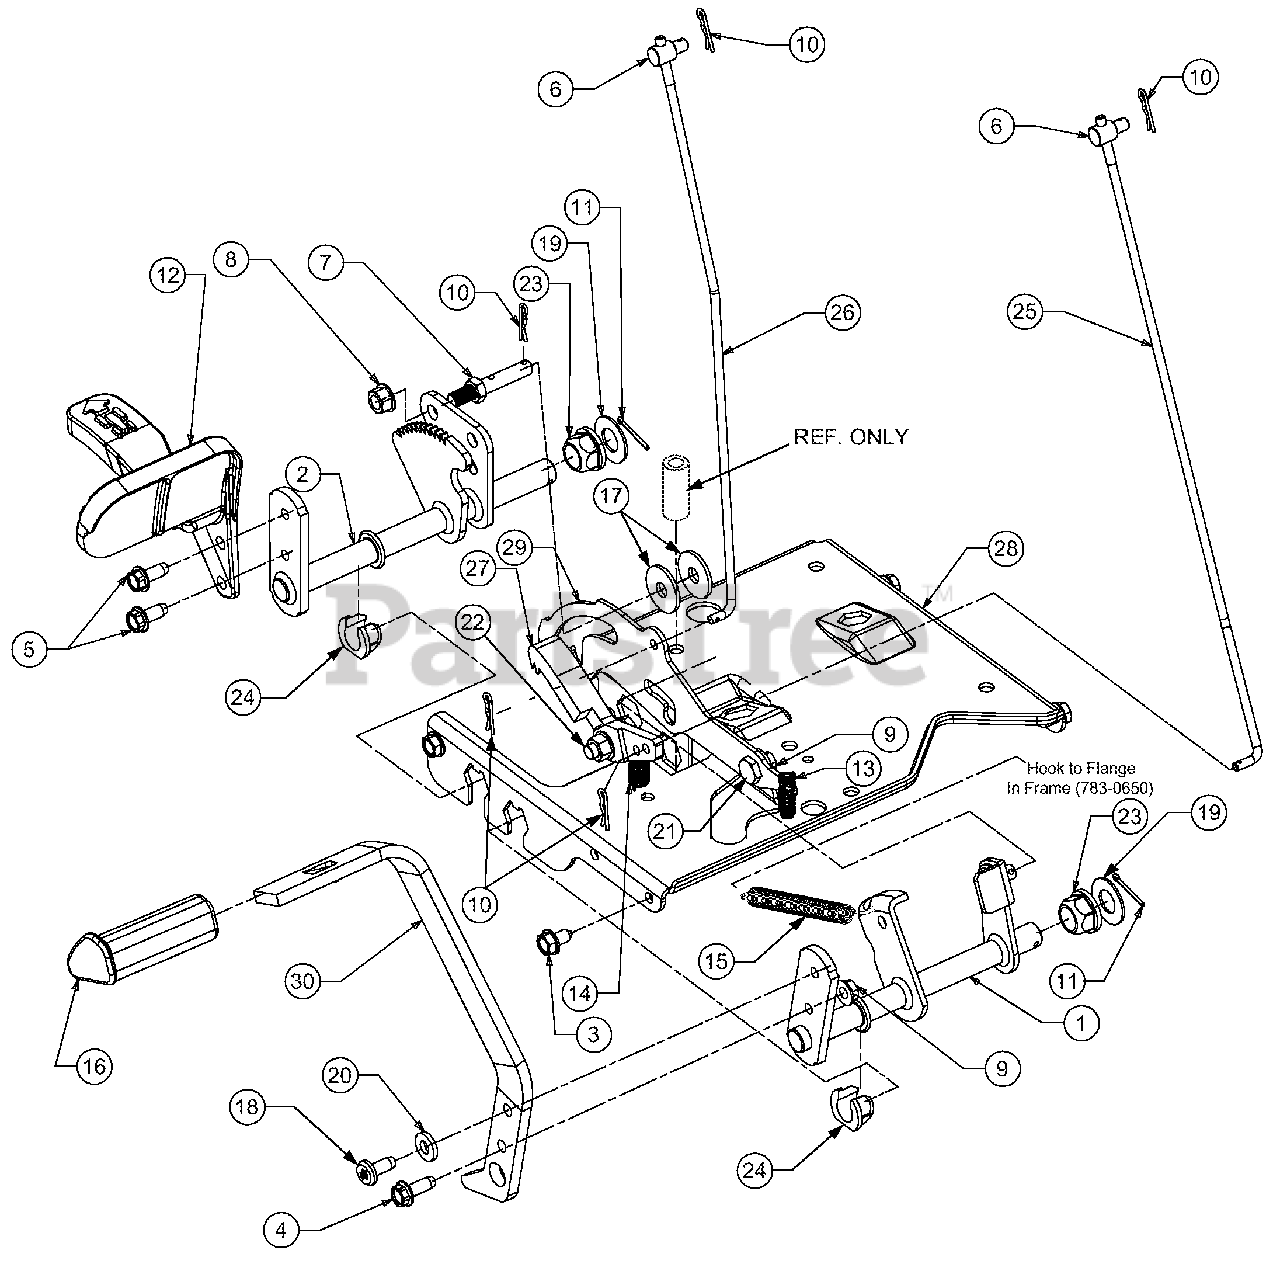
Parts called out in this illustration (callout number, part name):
3	Screw, Self-tapping, 5/16-12, 0.75
4	Screw, Self-tapping, 5/16-18, 0.875
5	Screw, 5/16-18, 0.750
6	Adjustment Ferrule 1/4-20 x 1.0
7	Pin, 3/8-16, 3/8 x 2.43 Lg
8	Nut, Flange Lock, 3/8-16
9	Nut, Flange Lock, 5/16-18, Gr5
10	Pin, Cotter, .072 Dia. x 1.13 Lg
11	Pin, Cotter, 3/32, 1.0
12	Pedal, Control
13	Spring, Compression, .405 x 1.17
14	Spring, Extension, .50 OD x 1.41 Lg
15	Spring, Extension, .50 Dia x 6.37 Lg
16	Pad, Brake, Control
17	Washer, Flat, .411 x 1.25 x .100
18	Screw, Torx Hd. Tapp. 5/16-18 x .75
19	Washer, Flat .64 ID x 1.24 x .06
20	Washer, Flat, .344 x .750 x .120
21	Shoulder, Screw .437 x 1.62 Lg
22	Screw, Shoulder, .500 Dia x .434
23	Bearing, Hex Flange
24	Bearing, Hex Flange, .628 ID, Split
25	Rod, Control, Cruise
26	Rod, Control, Brake Lock
27	Latch, Cruise
29	Bracket, Lockout, Hydro
30	Pedal, Brake
